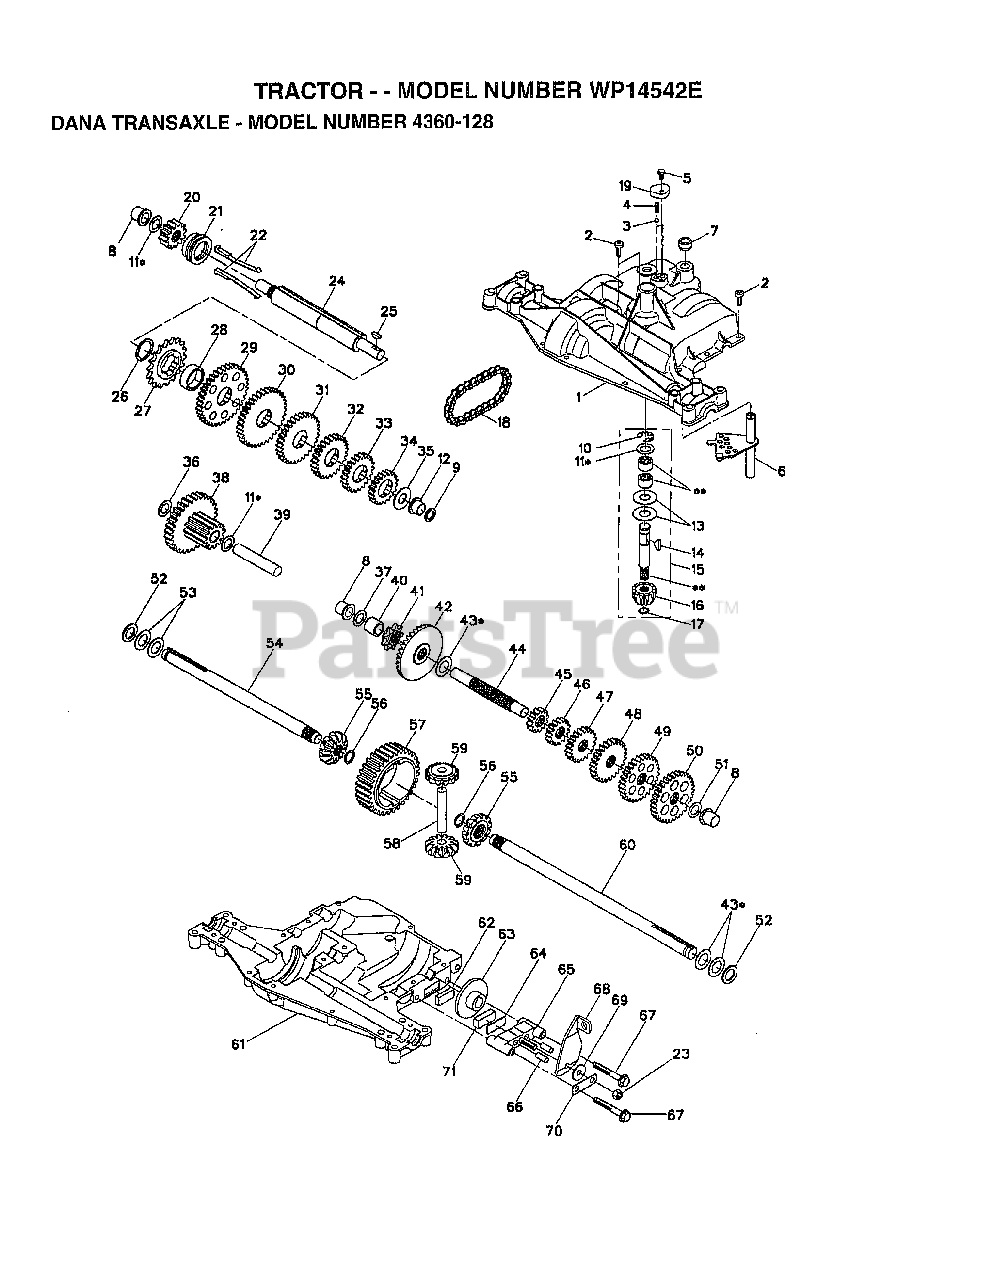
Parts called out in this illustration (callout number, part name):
1	HOUSING.UPPER(5305-P)
4	"SPRING, DETENT LT"
5	SCREW.TAPPING.1/4-20X.734
6	KIT SHIFTER ASM
9	SEAL.OIL.DAN.5508
10	RETAINING RING LT
11	ASM KIT SHIM 4689
12	BEARING.FLNG.5511
13	WASHER T
14	KEY WOODRUFF-DANA
15	INPUT SHAFT KIT 6250
16	PINION.BEVEL.12T(5620)
17	"RING,RETAINING LT"
18	"CHAIN,24 PTCH LT"
19	COVER.DETENT.(5584)
20	GEAR.SPUR.12T.(5627)
21	CLUTCH.COL.5467
22	ASM KIT CLTCH KEY
23	NUT.LOCK.5/16-24
24	SHAFT INTERM DANA
25	WOODRUFF KEY
26	"RING,RETAINING LT"
27	SPROCKET 18T T
28	SPACER YT
29	GEAR SPUR 37 TTH
30	GEAR SPUR 35 TTH
31	GEAR SPUR 30T
32	GEAR 25T LT
33	GEAR SPUR 22 TT
34	SPUR GEAR 19T
35	"WASHER, PLAIN LT"
36	WASHER 045
37	WASHER 031
38	ASSY.GEAR.6153 12T&30T
39	SHAFT IDLER
40	SPACER T
41	SPROCKET 9T LT
42	GEAR.BEVEL.36T(5621)
43	ASM KIT SHIM
44	SHAFT T
45	GEAR SPUR 12 TTH
47	GEAR SPUR 20T
48	"GEAR, SPUR 25T LT"
49	GEAR 28T T
50	"GEAR, SPUR 31T LT"
51	WASHER 060
52	NEOPRENE WASHER
53	WASHER 031
54	AXLE.LH(5528-1)
55	MITER 5270 12T.SPLINED
56	RING.RETAINING.(5270)
58	SHAFT T
59	MITER 5623.12T.IDLER
60	AXLE.RH.(5528-2) DANA
61	HOUSING.KIT (6088)
62	PUCK T
63	BRAKE DISC. T
64	SPACER LT
66	PIN T
67	SCREW.(5562) .5/16-18X2.35
69	WASHER LT
70	BRACKET, ANTI-ROTATION
71	PUCK T
